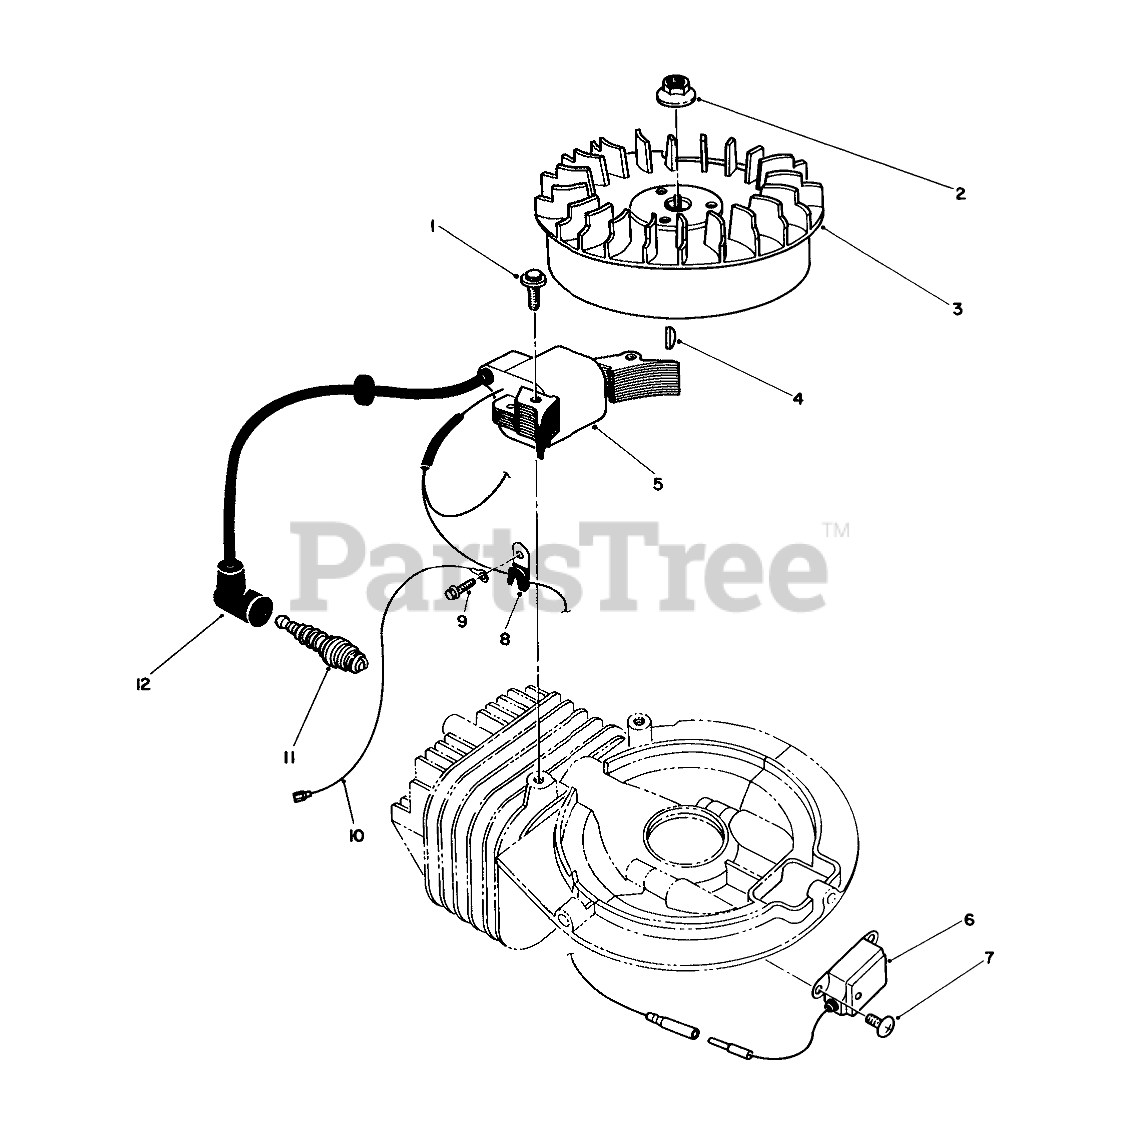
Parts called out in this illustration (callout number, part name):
1	Socket Hd. Capscrew
3	FLYWHEEL
5	MAGNETO COIL
6	MAGNETO MODULE
7	SCREW
8	CLAMP
11	Sparkplug
12	CAP-SPARKPLUG
